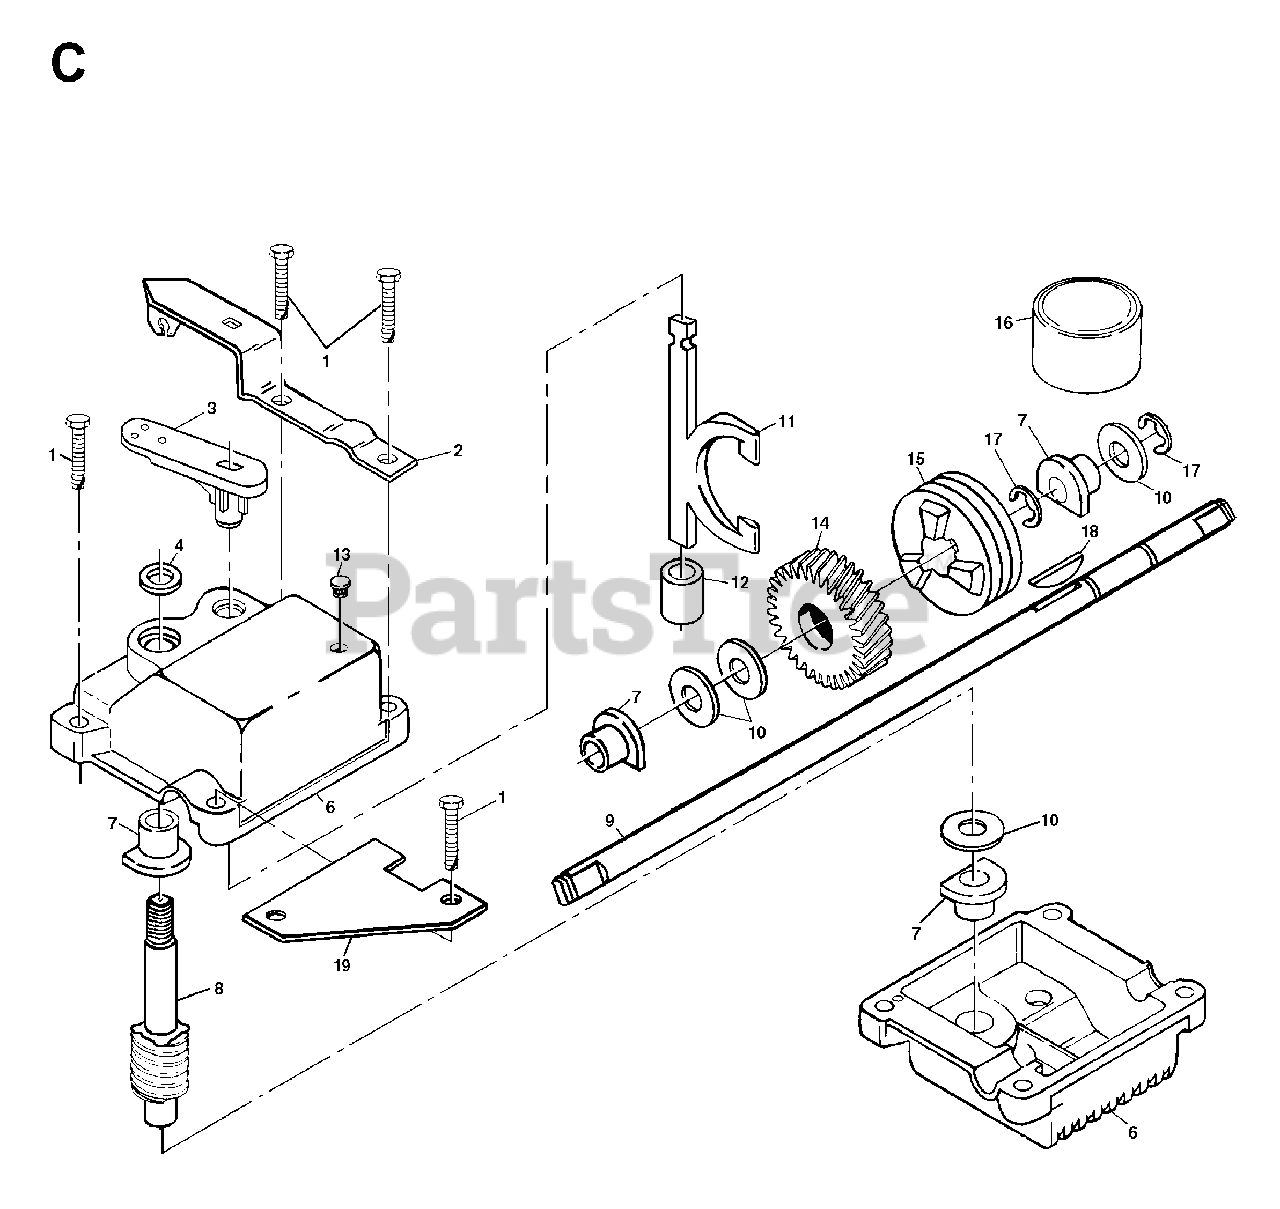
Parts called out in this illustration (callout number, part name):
1	DRIVE CONTROL
4	WAVE WASHER
5	BELT THERM .32
6	TAPPING SCREW
8	SELECTOR KNOB
9	SPRING RETAINER
12	DUST SHROUD PM
13	PINION GEAR
14	E-RING 7/16 RE
15	WHEEL & TIRE 8 X 2
20	DRV SHAFT TUBE PM
22	SPRING.EXTENSION
23	GEAR CASE ASMBLY
26	WASHER FLUT
27	PULLEY
28	FLANGED LOCKNUT 3/8-16 ZINC
36	HEX FLANGE LOCKNT
37	NUT
